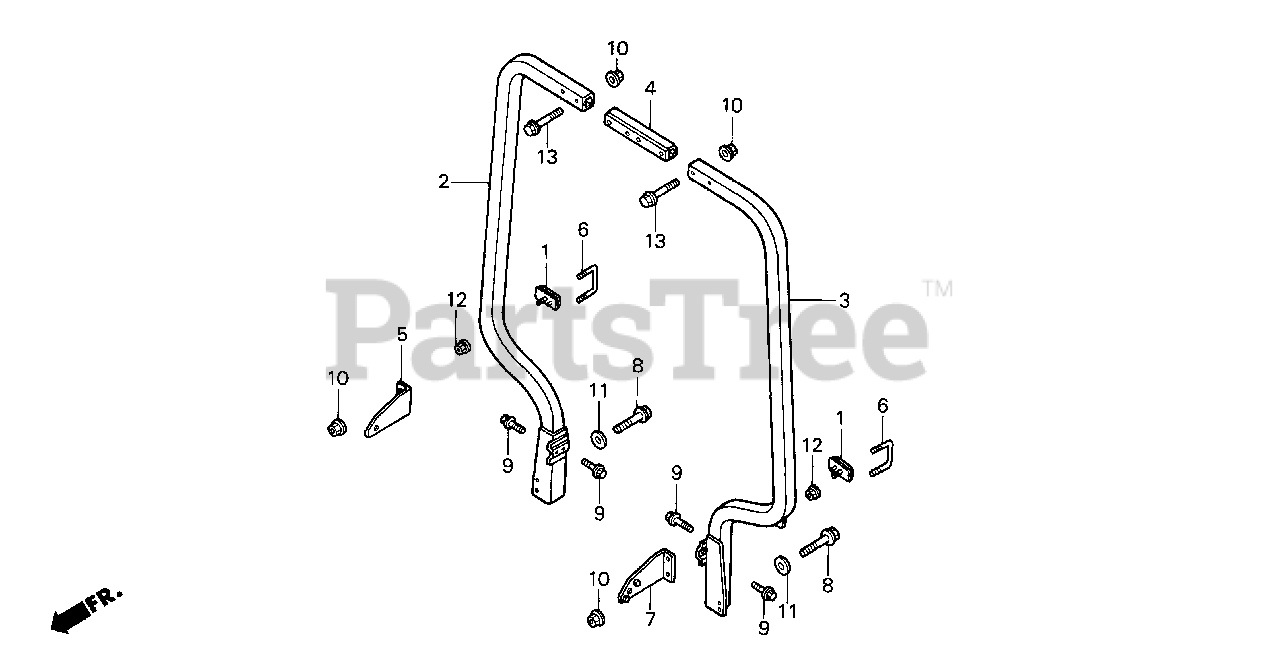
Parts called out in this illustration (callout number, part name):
1	REFLECTOR, REFLEX
2	STRUCTURE, R. ROLL OVER PROTECTIVE *NH1* (BLACK)
3	STRUCTURE, L. ROLL OVER PROTECTIVE *NH1* (BLACK)
4	JOINT, ROLL OVER PROTECTIVE STRUCTURE
5	PLATE, R. SEAT BELT
6	U-BOLT (10X74)
7	PLATE, L. SEAT BELT
8	BOLT, FLANGE (10X30)
9	BOLT, HEX. (10X25)
10	NUT, U (10MM)
11	WASHER (10.3X25)
12	NUT, FLANGE (5MM)
13	BOLT, FLANGE (10X60)
